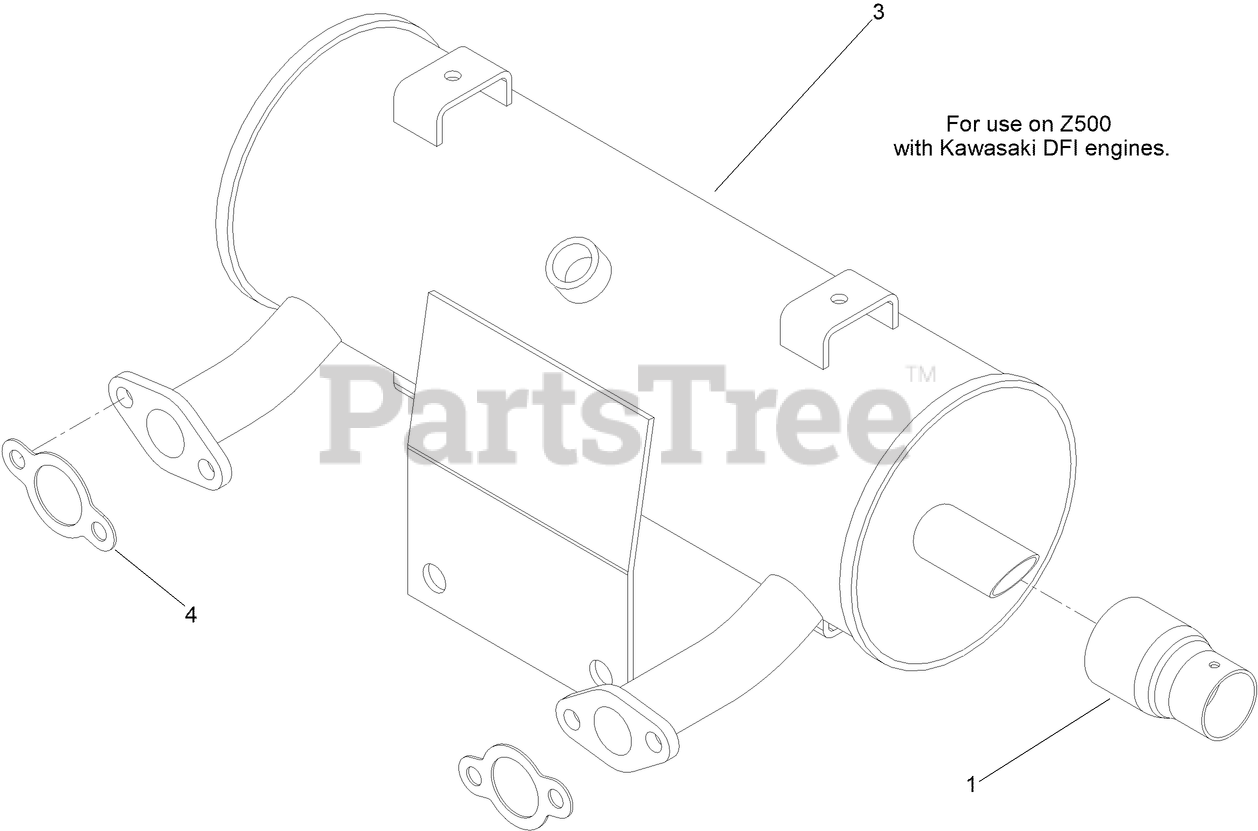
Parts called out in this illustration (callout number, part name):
1	SPARK ARRESTOR, 1.25 I.D.
3	MUFFLER
4	GASKET-EXHAUST
